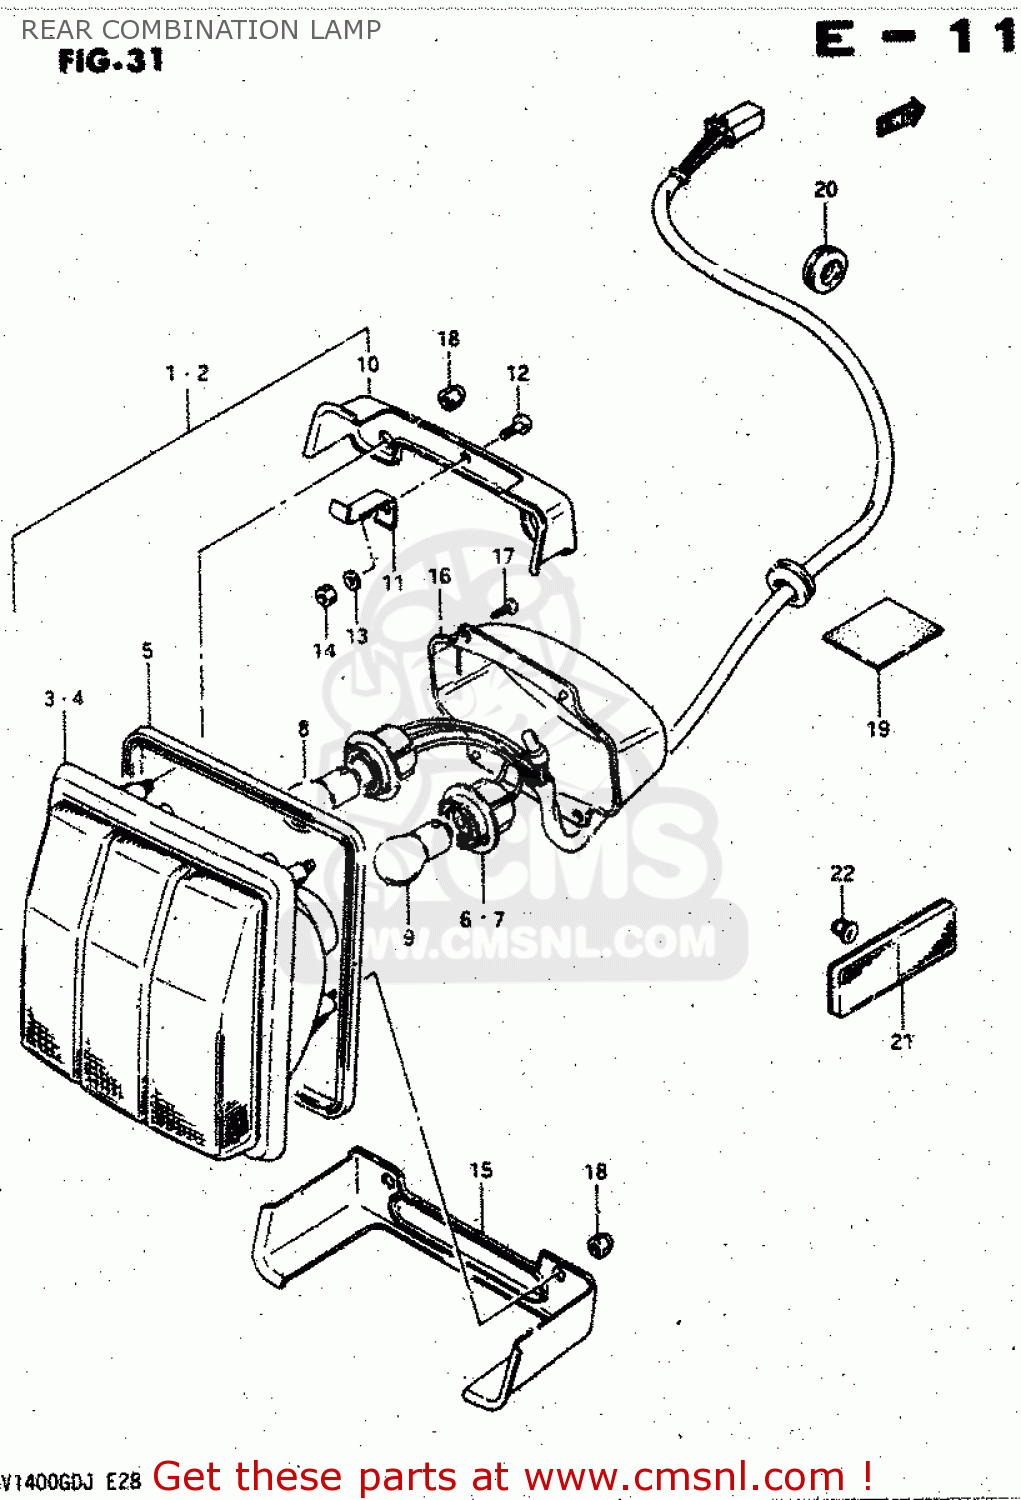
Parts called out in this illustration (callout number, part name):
1	LAMP ASSEMBLY,REAR COMBINATION
2	LAMP ASSEMBLY,REAR COMBINATION
3	LAMP UNIT,RIGHT
4	LAMP UNIT,LH
5	GASKET,REAR COMBINATION LAMP BASE
6	SOCKET, RH
7	SOCKET,LEFT
8	BULB(12V23/8W,TOKAI DENSO)
9	BULB(12V23W,STANLEY,A4577A)
10	BRACKET,REAR COMBINATION LAMP,UPPER
11	BRACKET, UPPER NO.2
12	SCREW
13	LOCK WASHER
14	NUT
15	BRACKET,REAR COMBINATION LAMP,LOWER
16	COVER
17	SCREW
18	NUT 6MM
19	COVER,HARNESS
20	GROMMET
21	REFLEX REFLECTOR ASSY,RR SIDE
22	NUT 5MM
